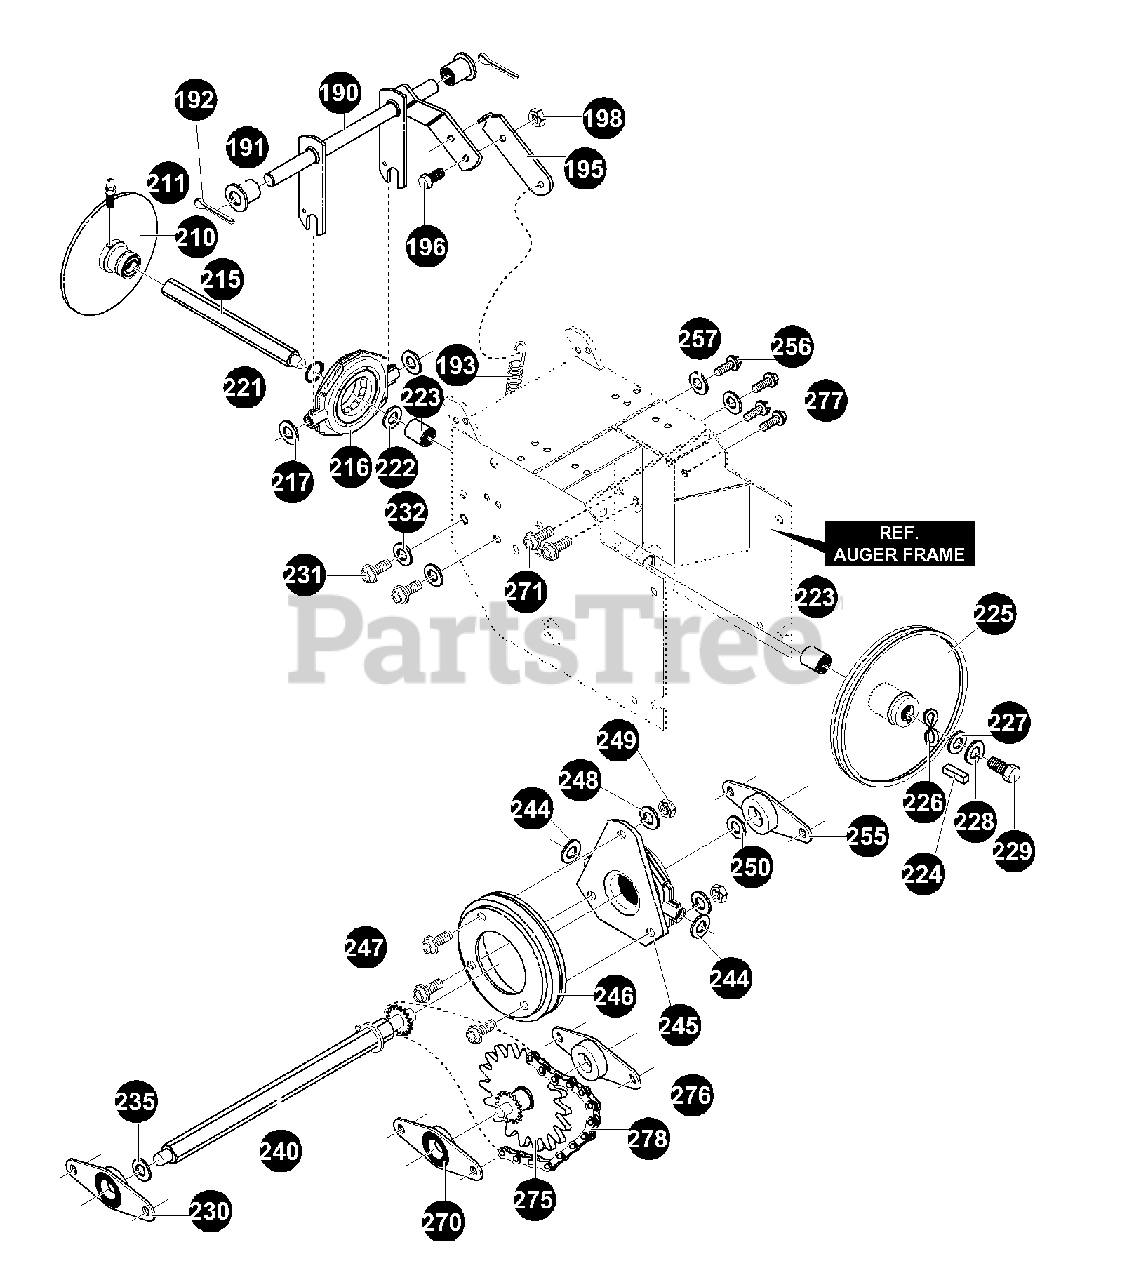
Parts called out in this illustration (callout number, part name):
190	LEVER, ASSY TRACTION CLUTCH
191	BEARING, FLANGED
192	COTTER PIN .125 DIAX1.00LG
193	SPRING, RETURN
195	LEVER, SPRING TRAC CLUTCH
196	SCREW, 1/4-20X.63
198	NUT, 1/4-20 REGHEXCTRLK
210	DISC, ASSY FRICTION WHEEL
211	ZERK, GREASE
215	SHAFT, HEX TRACTION
216	BEARING, TRUNION
217	FLATWASHER, .680X1.12X.060
221	RING, RETEX 1.16X.05TRU
222	FLATWASHER, .680X1.12X.060
223	BEARING, BALL 6203-2AA-C3
224	KEY, SQUARE .18SQX,63LG
225	PULLEY, V3L 6.50X.56
226	WASHER, WAVE .675X1.00X.020
227	FLATWASHER, .281X1.00X.063
228	WASHER, RSPTLK .263X.49X.07
229	SCREW 1/4-20X.75
230	BEARING & RETAINER ASSY
231	SCREW 5/16-18X.50 WAHHTAP
232	WASHER, HVSPTLK .328X.60X.09
235	WASHER, SP .502X.75X.0605
240	SHAFT & SPROCKET ASSY
244	FLATWASHER .505X1.00X.06
245	BEARING, TRUNION CLUTCH
246	WHEEL, ASSY FRICTION DISC
247	SCREW, 1/4-20X.63
248	WASHER, RGSPTLK .263X.49X.07
249	NUT, 1/4-20 REGHEX
250	WASHER, SP .502X.75X.0605
255	BEARING & RETAINER ASSY
256	SCREW, 5/16-18X.50 WAHHTAP
257	WASHER, HVSPTLK .328X.60X.09
270	BEARING & RETAINER ASSY
271	SCREW, 5/16-18X.50 WAHHTAP
275	JACK, ASSY #41-36T&7T W/PBRG
276	BEARING & RETAINER ASSY
277	SCREW 5/16-18X.50 WAHHTAP
278	CHAIN ROLLER #42 X 40P
